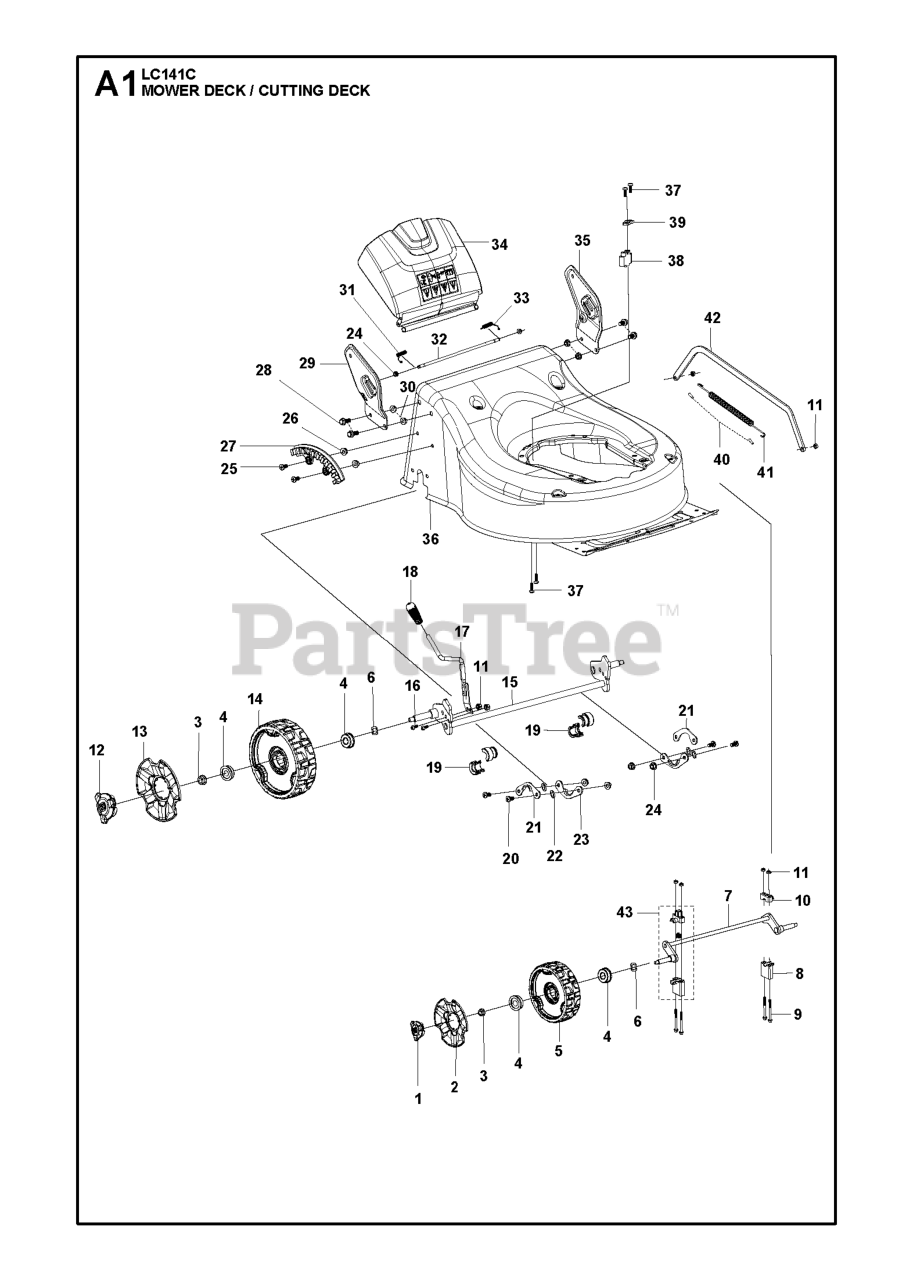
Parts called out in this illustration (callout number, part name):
1	WHEEL COVER 6" #25340700101
2	COVER 7 WHEEL COVER
3	LOCKING BOLT M8,GB6187.1 #2680
5	WHEEL ASSY 7 WHEEL
6	WASHER Ï?12 #26800706202
7	FRONT AXLE ASSY
11	LOCKING BOLT M6,GB889.1 #26800
12	WHEEL COVER 8" #25341000101
13	WHEEL COVER 8" #25341100101
14	WHEEL #25341300101
15	REAR AXLE ASSY
16	WASHER M6*14 #26800203001
17	HANDLE ASSY
18	KNOB HEIGHT ADJUSTMENT #25341
19	COVER AXLE #25235300101
20	SCREW M6*16 #26800204601
21	FIXING PLATE #26300314601
22	O-RING #25100175201
23	FIXING PLATE #26300124401
24	LOCK NUT M6,GB/T6187.1-2000 #2
27	SEGMENT #25214200102
28	BOLT M8*16 #26800606401
29	BRACKET RH
31	SPRING #26801125501
33	BRACKET #26801125401
40	TUBING #29000300101
41	SPRING #26801103903
42	CONNECTING ROD
